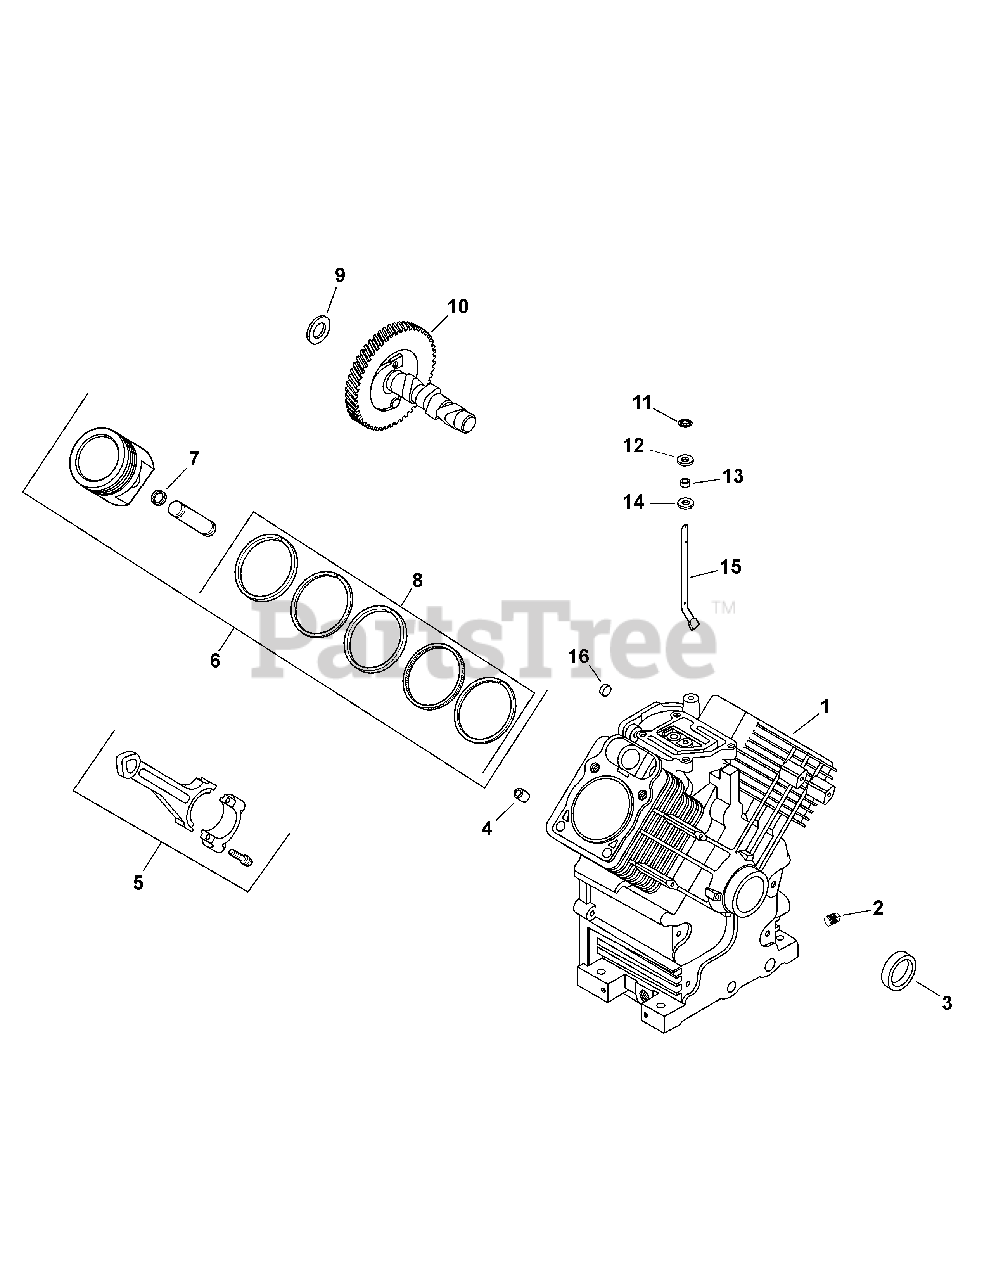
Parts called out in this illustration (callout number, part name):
1	Crankcase
2	Plug, Pipe 3/8"
4	Pin, Locating
5	Connecting Rod (STD)
5	Connecting Rod (.25)
6	Kit, Piston w/ Ring (STD) (Includes 7, 8)
6	Kit, Piston w/ Ring (.08)
6	Kit, Piston w/ Ring (.25)
6	Kit, Piston w/ Ring (.50)
7	Retainer, Piston Pin
8	Ring Set, Piston (STD)
9	Camshaft Shim (Yellow .034")
9	Camshaft Shim (White .028")
9	Camshaft Shim (Blue .03")
9	Camshaft Shim (Red .032")
9	Camshaft Shim (Green .036")
9	Camshaft Shim (Gray .038")
9	Camshaft Shim (Black .04")
10	Kit, Camshaft
11	Retainer, Ring
12	Washer, Flat 9MM
13	Seal, Governor Cross Shaft
14	Washer, Flat 11/32"
15	Shaft, Governor Cross
